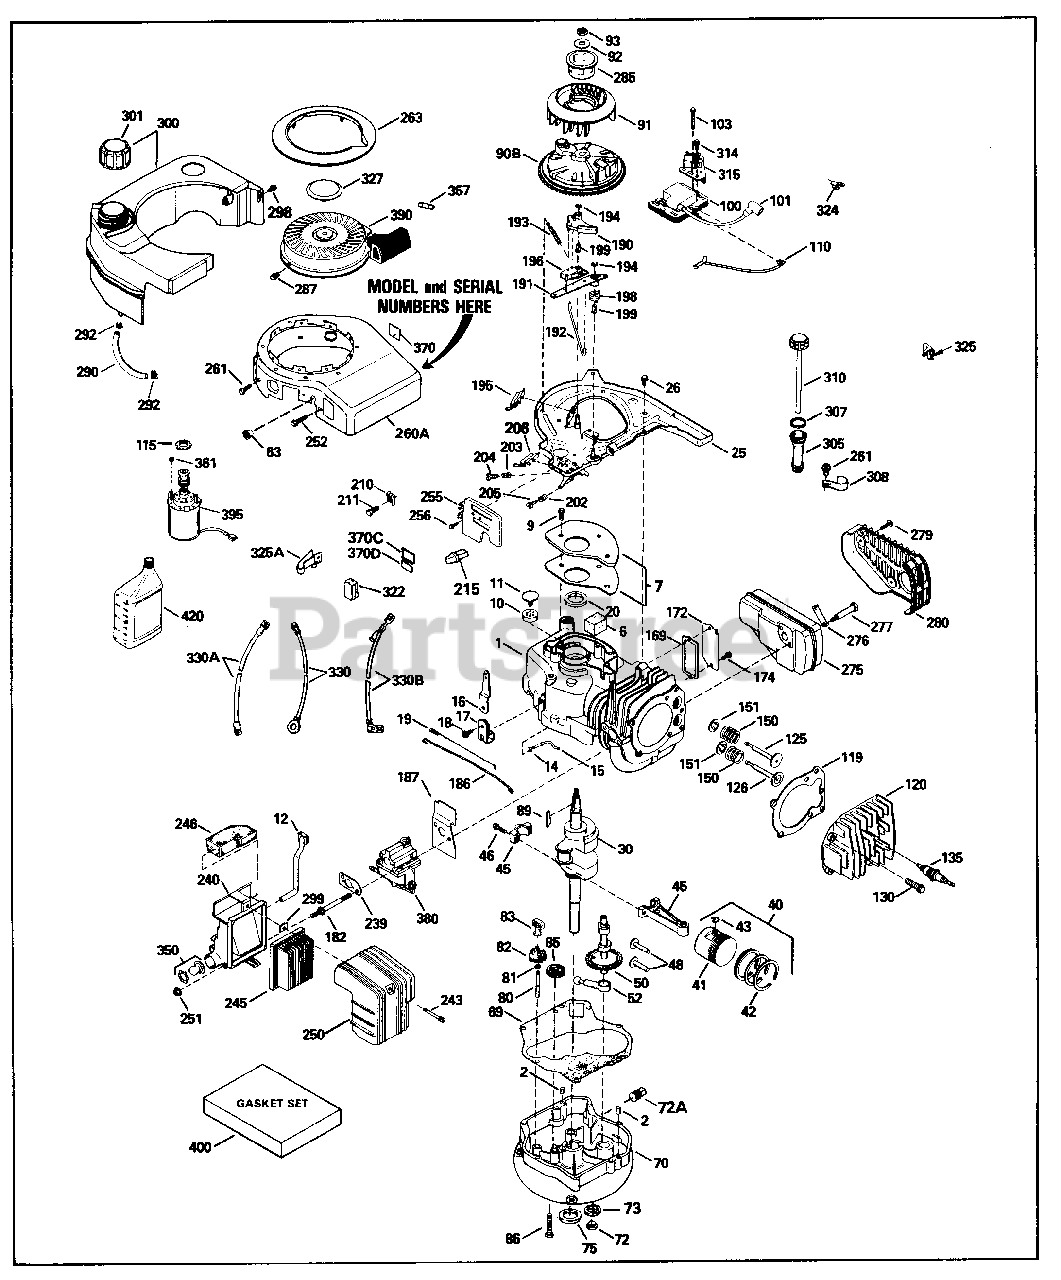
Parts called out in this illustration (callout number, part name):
1	"Cylinder (Incl. 2, 10, & 20)
2	Dowel Pin
6	Breather Element
9	Screw, 10-24 x 1/2"
10	Breather Valve Body
11	Check Valve
12	Breather Tube
12C	* Breather Cover & Gasket
14	Flat Washer
15	Governor Rod (Machined)
16	Governor Lever
17	Governor Lever Clamp
18	Screw, 8-32 x 5/16"
19	Governor Spring
20	Oil Seal
25	Blower Housing Baffle Ass'y. Incl.l95
26	Screw, 1/4-20 x 5/8"
30	Crankshaft Ass'y.
40	Piston,Pin,Ring Set (Std.)
40	Piston,Pin,Ring Set (.010 OS)
40	Piston,Pin,Ring Set (.020 OS)
41	Piston & Pin Ass'y.(Std.) (Incl. 43)
41	Piston & Pin Ass'y.(.010 OS)(Incl.43)
41	Piston & Pin Ass'y.(.020 OS)(Incl.43)
42	Ring Set (Std.)
42	Ring Set (.010 OS)
42	Ring Set (.020 OS)
43	Piston Pin Retaining Ring
45	Connecting Rod Ass'y. (Incl. 46)
46	Connecting Rod Bolt
48	Valve Lifter
50	Camshaft (MCR)
52	Oil Pump Ass'y.
69	* Mounting Flange Gasket
70	Mounting Flange (Incl. 72 thru 85)
72	Oil Drain Plug
73	Drain Plug Gasket
75	Oil Seal
80	Governor Shaft
81	Flat Washer
82	Governor Gear Ass'y. (Incl.81)
83	Governor Spool
85	Idler Gear
86	Screw, 1/4-20 x 1-9/16"
89	Flywheel Key
91	Flywheel Fan
92	Belleville Washer
93	Flywheel Nut
100	Solid State Ignition
101	Spark Plug Cover
103	Screw, Torx T-15, 10-24 x 1"
110	Ground Wire
119	* Cylinder Head Gasket
120	Cylinder Head
125	Exhaust Valve (Std.) (Incl. 151)
125	Exhaust Valve (1/32" OS) (Incl. 151)
126	Intake Valve (Std.) (Incl. 151)
126	Exhaust Valve (1/32" OS) (Incl. 151)
130	Screw, 5/16-18 x 1-1/2"
135	Resistor Spark Plug (RJ19LM) also ava ilable in Packaged Part #740081
150	Valve Spring
151	Lower Valve Spring Cap
169	* Valve Spring Box Gasket
172	Valve Spring Box Cover
174	Screw, 10-24 x 9/16"
177	Carburetor Mounting Stud
186	Governor Link
187	* Carburetor Mounting Spacer
190	Brake Lever Ass'y.
191B	Brake Control Lever
192	Brake Control Lever Link
193	Brake Spring
194	Retaining Ring
195	Terminal Ass'y.
198	Brake Control Lever Spring
199	Brake Levers Bushing
202	Compression Spring
203	Compression Spring
204	Screw, 5-40 x 7/16"
205	Screw, 6-32 x 21/32"
215	Control Knob
239	* Carburetor to Air Cleaner Gasket
240	Air Cleaner Body (Incl.239,299 & 350)
243	Screw, 10-32 x 2-3/32"
245	Air Filter (Paper) (also available in Packaged Part #740031B for model VLV only) (also available in Packaged Pa rt #740061C for model OH195)
250	Air Cleaner Cover
251	Lock Nut 1/4-20
255	Control Plate
256	Screw, 8-32 x 21/64"
261	Screw, 1/4-20 x 11/16"
262	Screw, 1/4-20 x 1-1/2"
263	Trim Ring
275	Muffler Ass'y.
276	Locking Plate
277	Screw, 5/6-18 x 2-11/32"
285	Starter Cup
287	Screw, 8-32 x 21/64"
290	Fuel Line
292	Fuel Line Clamp
299	"U" Type Nut Clip
300	Fuel Tank (Incl. 301)
301	Fuel Cap (Red)
305	Oil Fill Tube
307	"O" Ring
308	Fill Tube Clip
310	Oil Dipstick
327	Starter Plug this)
346A	Screw, 10-32 x 35/64"
350	Primer
370	Control Decal
380	Carburetor (Incl. 187 & 239)
390	Rewind Starter
400	* Gasket Set (Incl. items marked PK in notes). Incl. part #'s 27234A (1),36 005A (1), 36032 (1), 36035 (1),36048 (1), 36061 (1)
420	4 Cycle Oil, SAE 30 (Quart)
999	Summer Maintenance Kit (incl. Oil, Sp ark Plug, Air Cleaner, & Ultra Fresh)
